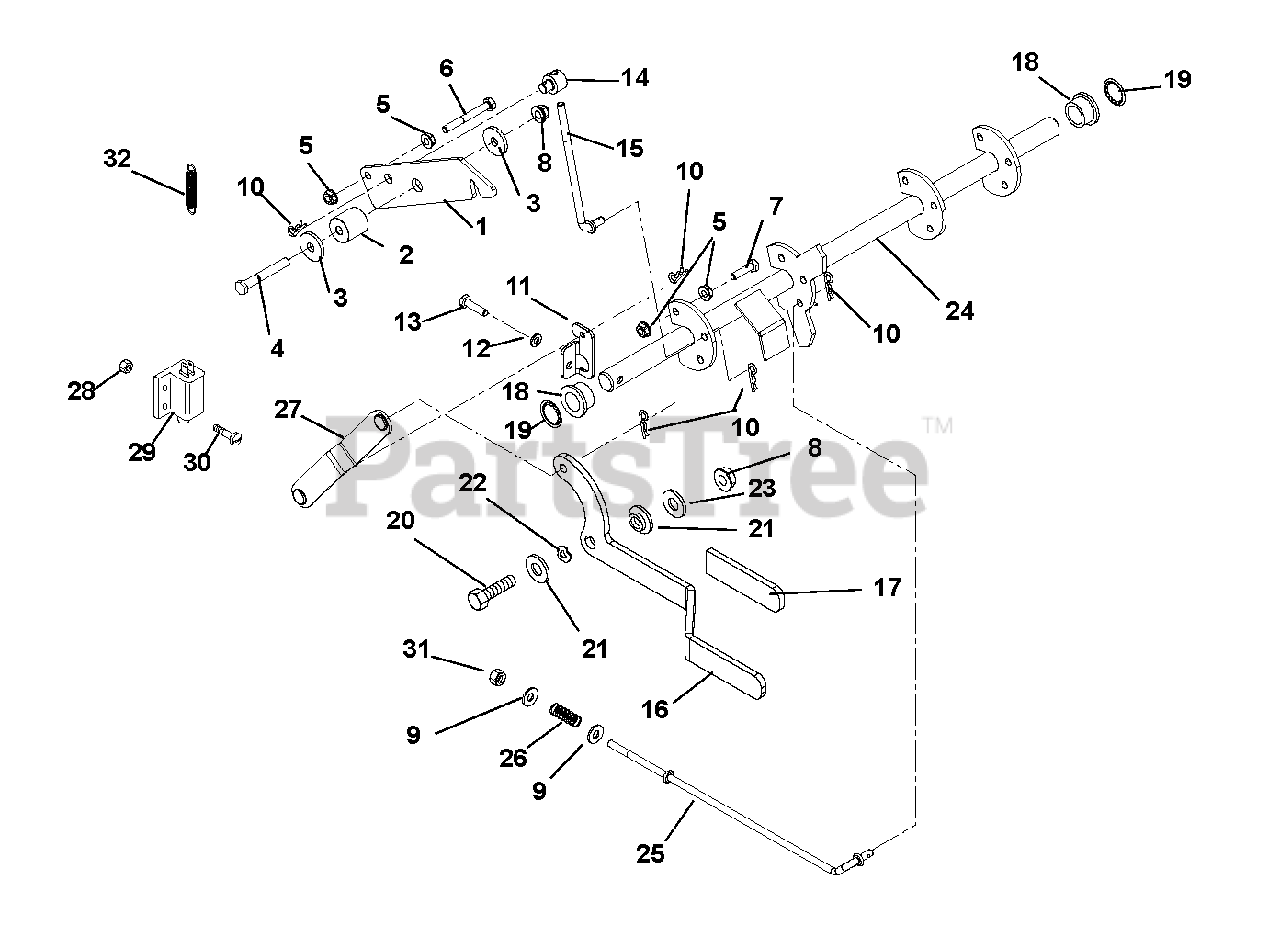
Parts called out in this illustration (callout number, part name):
1	Latch, Neutral
3	Washer, Flat Steel .344 x 1.125 x .135
4	Bolt, Hex .31-18 x 2.25 Grade 5
5	Nut, Locking Flange .250-20
6	Bolt, Hex .25-20 x 2.25 Grade 5
7	Bolt, Hex .25-20 x 1.00 Grade 5
8	Nut, Flange Nyloc 5/16-18
9	Washer, Flat Steel .312 x .734 x .065
10	Pin, Hair Internal .08 x .18 x 1.18
11	Crank, Parking Brake
12	Washer, Locking .31 x .078 Regular
13	Bolt, Hex .31-18 x 1.00 Grade 5
14	Trunnion, Brake
15	Brake, Link
16	Handle, Parking Brake
17	Grip, Parking Brake
18	Bushing, Flanged .750 x 1.000 x .625 x 1.250
19	Push Nut, .745 Shaft
20	Bolt, Hex .31-18 x 1.75 Grade 5
21	Bushing, Flange .325 x .501 x .250 x 1.12
22	Washer, Wave .50 x .75 x .015
23	Washer, Flat Steel, .328 x .87 x .179
24	Weldment, Brake Shaft
25	Rod, Brake
26	Spring, Compression .045 x .50 x 1.187
27	Link, Parking Brake
28	Nut, Locking Nylon 10-24 with Insert
29	Switch, Double Pole
30	Screw, Machine 10-24 x .75
31	Nut, Locking Nylon .250-20
32	Spring, Tension .069 x .62 x 3.50
